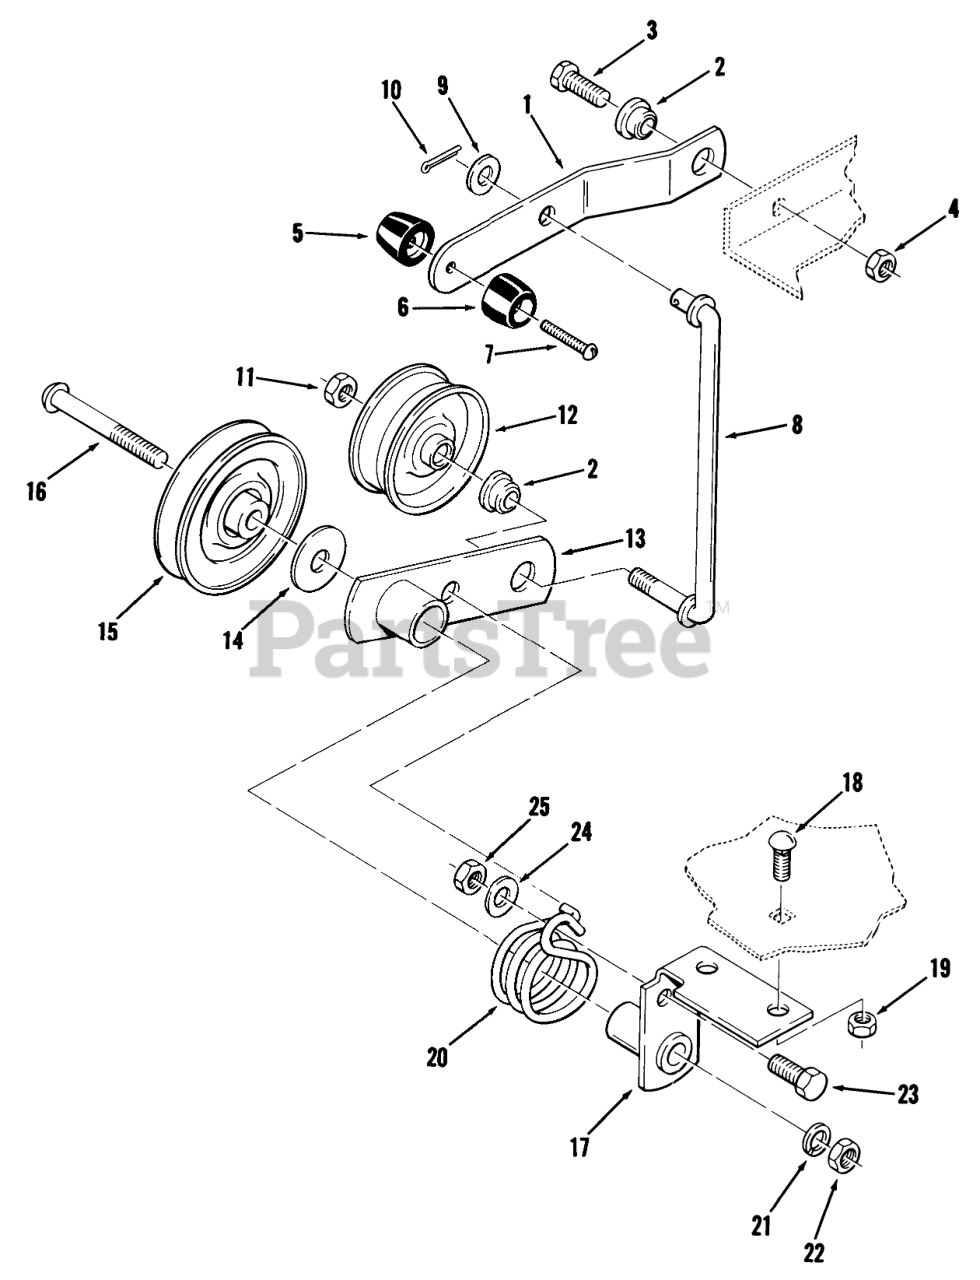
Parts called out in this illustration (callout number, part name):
1	LEVER-DR CLUTCHING
2	SPACER-BRAKE LINK
3	BOLT
4	Nut
5	KNOB
6	KNOB
7	BOLT-4
9	Washer
10	Pop Rivet
11	Nut
12	Pully-Idler
13	ASSY-IDLER ARM
14	WASHER
15	PULLEY-IDLER
16	SCREW 3/8-16X23/4
17	Idler Arm Support
18	CARRIAGE BOLT -4
19	Nut
20	SPRING-TORSION
21	LOCKWASHER
22	Nut
23	Bolt
24	Washer
25	Nut
